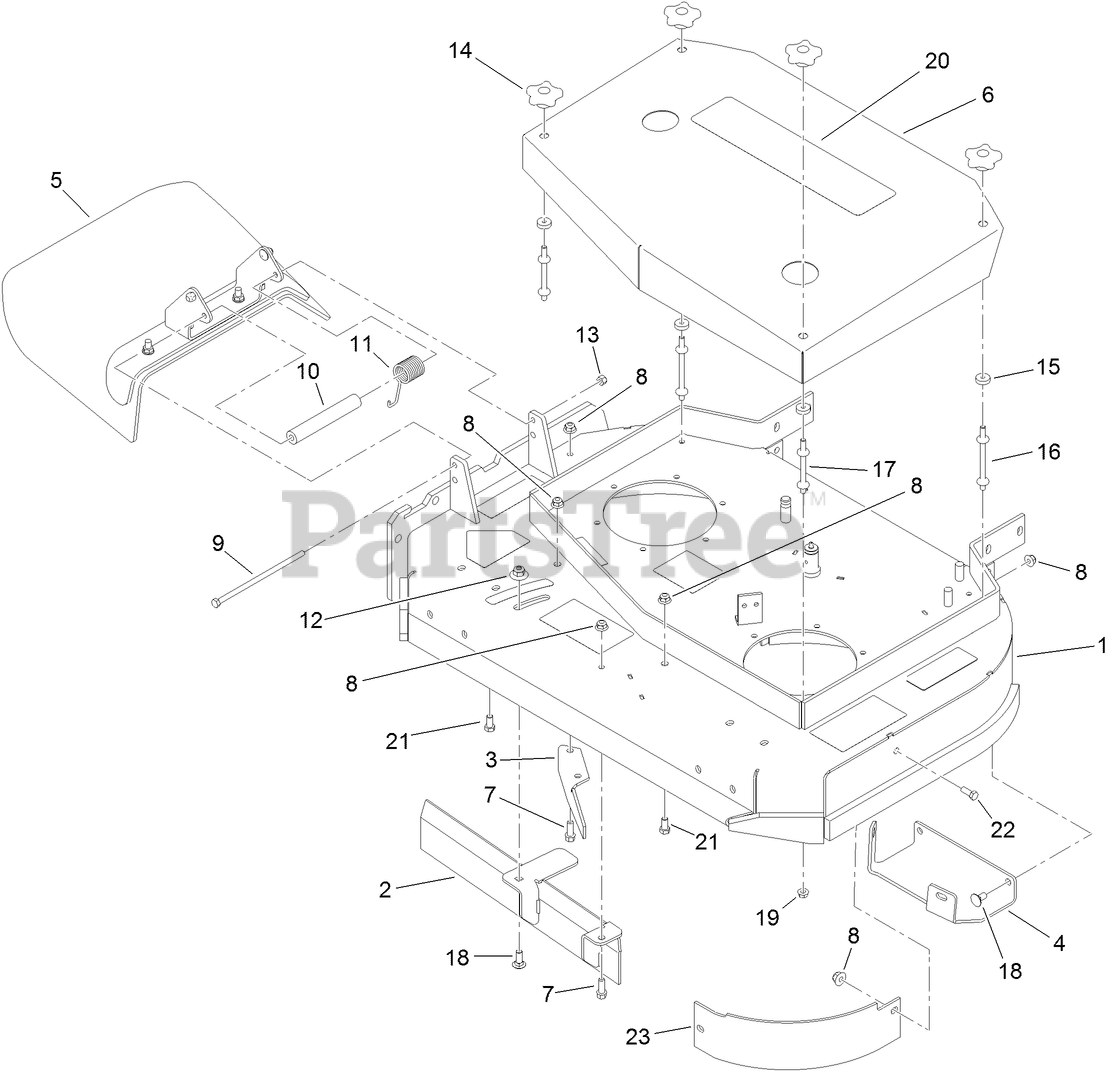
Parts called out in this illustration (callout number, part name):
1	DECK ASM
3	BAFFLE-DISCHARGE
4	PLATE-SKID
5	DEFLECTOR ASM
6	COVER-DECK
7	SCREW-HWH
8	NUT-HF, NI
9	SCREW-HH
10	SPACER
11	SPRING-TORSION
12	NUT-FLANGE, NI
13	NUT-LOCK, NI
14	KNOB-HANDLE
15	WASHER
16	STUD-SHIELD, BELT (LONG)
17	STUD-SHIELD, BELT (SHORT)
18	BOLT-CARR
19	NUT-HF
21	SCREW-HH
22	SCREW-HH
23	BAFFLE-FRONT, LH
